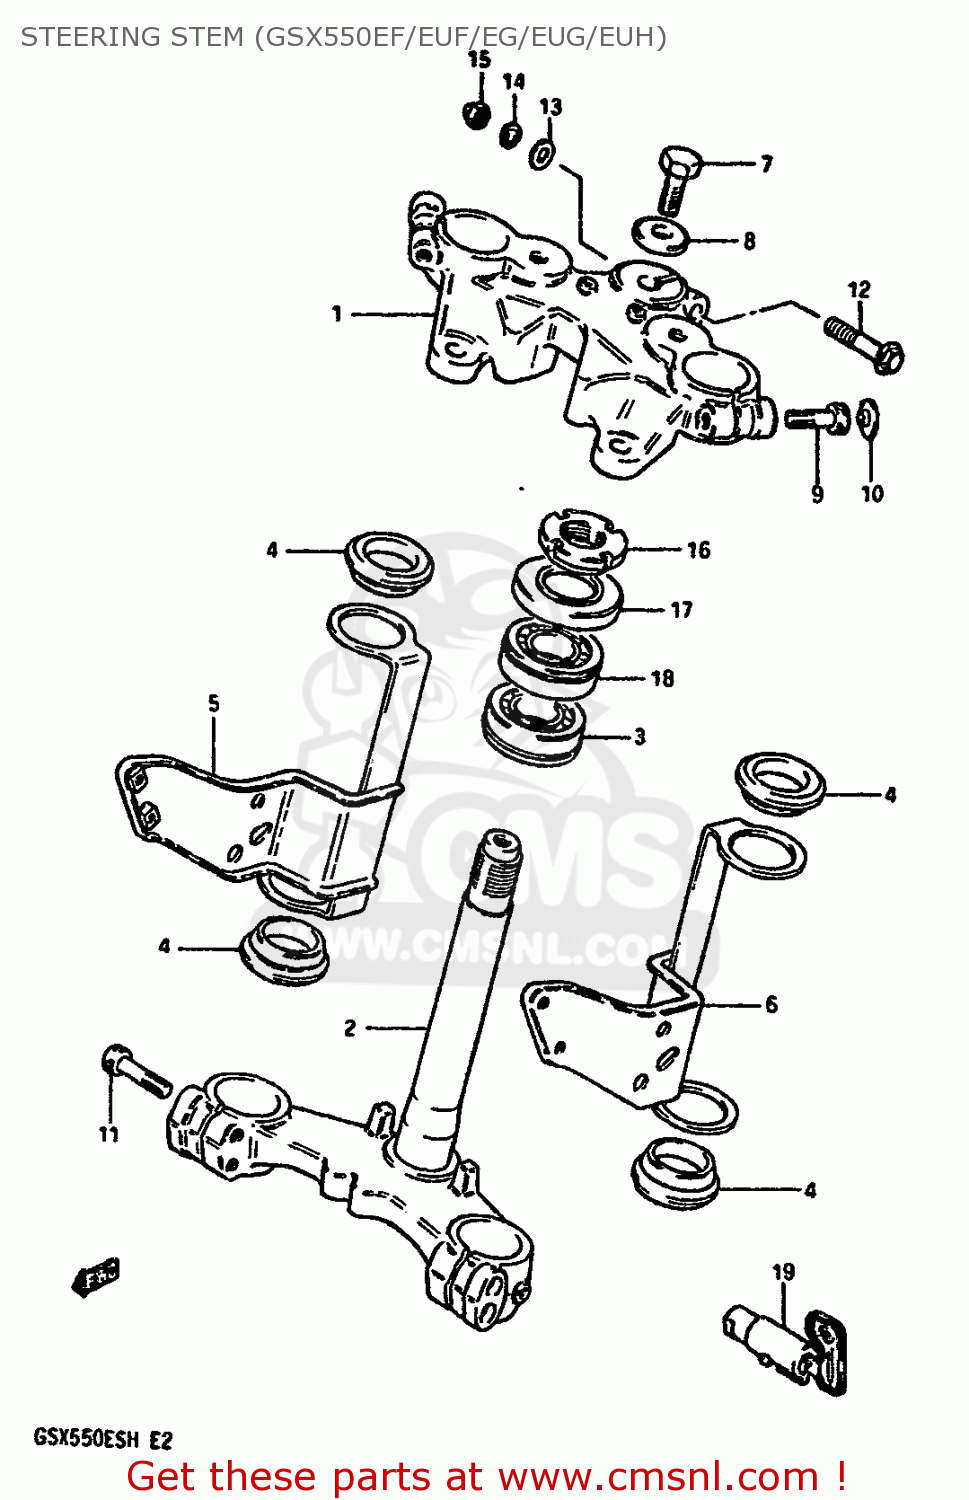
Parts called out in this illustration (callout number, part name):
1	HEAD,STEERING STEM
2	STEM,STEERING
3	BEARING
4	CUSHION,HEADLAMP BRACKET
5	BRACKET,HEADLAMP,RIGHT
6	BRACKET,HEADLAMP,LEFT
7	NUT,STEM HEAD
8	WASHER,STEERING STEM B
9	BOLT,FORK INNER TUBE FITTING
10	CAP(OD:20)
11	BOLT, REAR (8X30)
12	BOLT, UPPER
13	WASHER
14	WASHER,LOCK,8.
15	NUT,M8X1.25X12
16	NUT,STEERING STEM
17	DUST SEAL,STEERING UPR
18	TAPER,ROLLER BEARING
19	LOCK ASSY,STEERING(NEIMAN)
